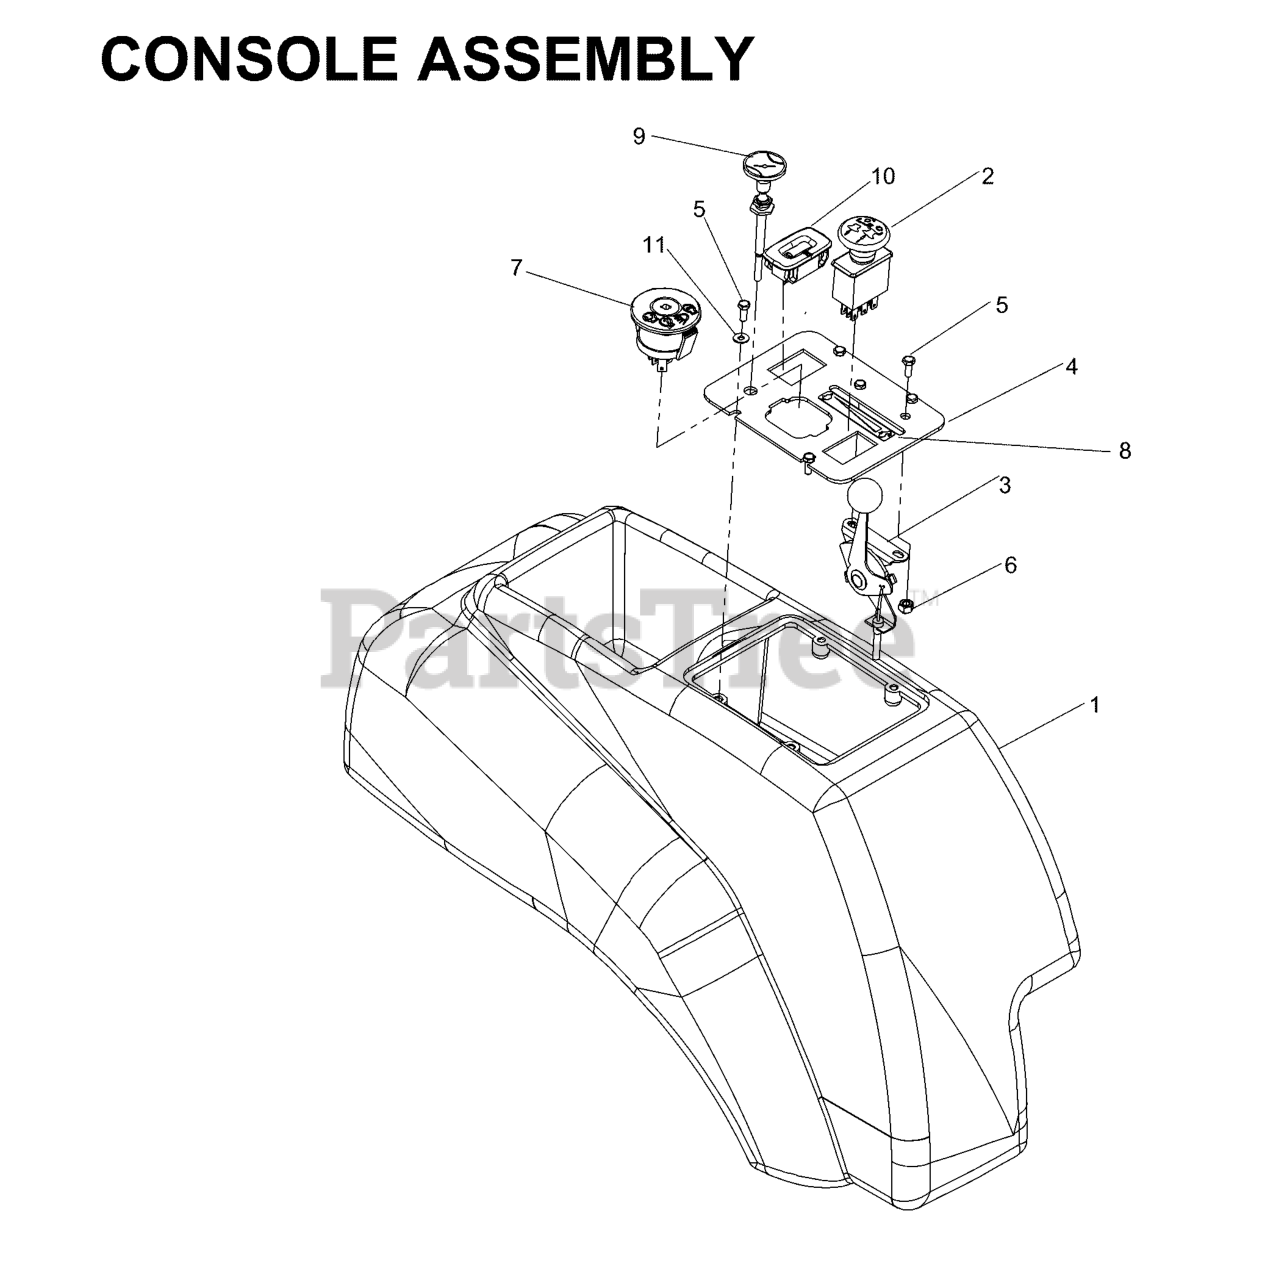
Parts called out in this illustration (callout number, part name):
1	FENDER CONSOLE
2	RP.SWITCH, BLADE
3	THROTTLE CABLE
4	CONSOLE PLATE, BLACK
5	HCS #10-24 X 1/2
6	NUT 10-24 NYLOC
7	RP IGNITION SWITCH
8	DECAL, THROTTLE
9	CHOKE CABLE
10	HOUR METER
11	WASHER #10
